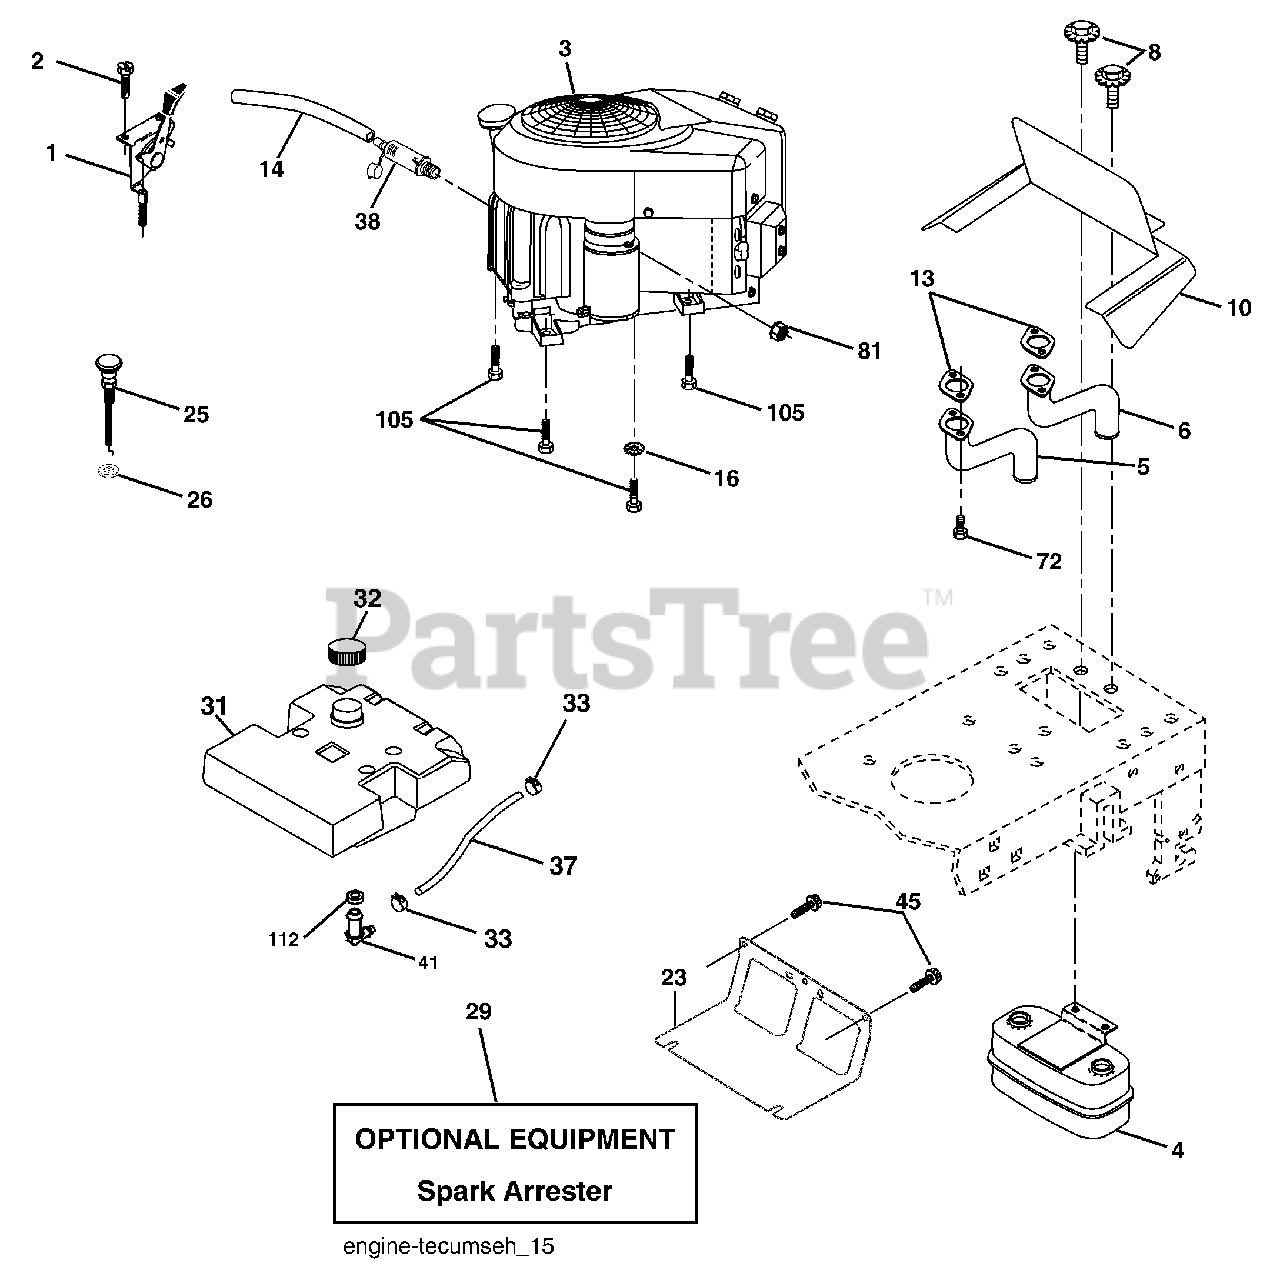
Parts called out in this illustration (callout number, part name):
1	Control Throttle
2	Screw Hwhd Hi-Lo #13-16 x 3/4
4	Muffler Asm Twin Lo-Tone
5	Pipe Exhaust LH
6	Pipe Exhaust RH
8	Bolt 5/16-18 UNC x 3/4 w/Sems
10	Shield Muffler
13	Muffler Gasket
14	Tube Drain Oil
16	Washer Lock Ext Tooth 3/8
23	Shield Heat
25	Choke Control
26	Nut, Keps 3/8-24 UNF
29	Kit Spark Arrestor (Flat Scrn)
31	Tank Fuel
32	Cap Asm Fuel
33	Clamp Hose Black
37	Line Fuel
38	Plug Grain Oil
41	Stem Tank Fuel
45	Screw Hexwsh Thdr 3/8-16 x 3/4
72	Screw Socket Head 5/16-18 x 1
81	Nut Keps Hex 1/4-20 Unc
105	Screw Thdrol 3/8-16 x 1
112	Bushing
